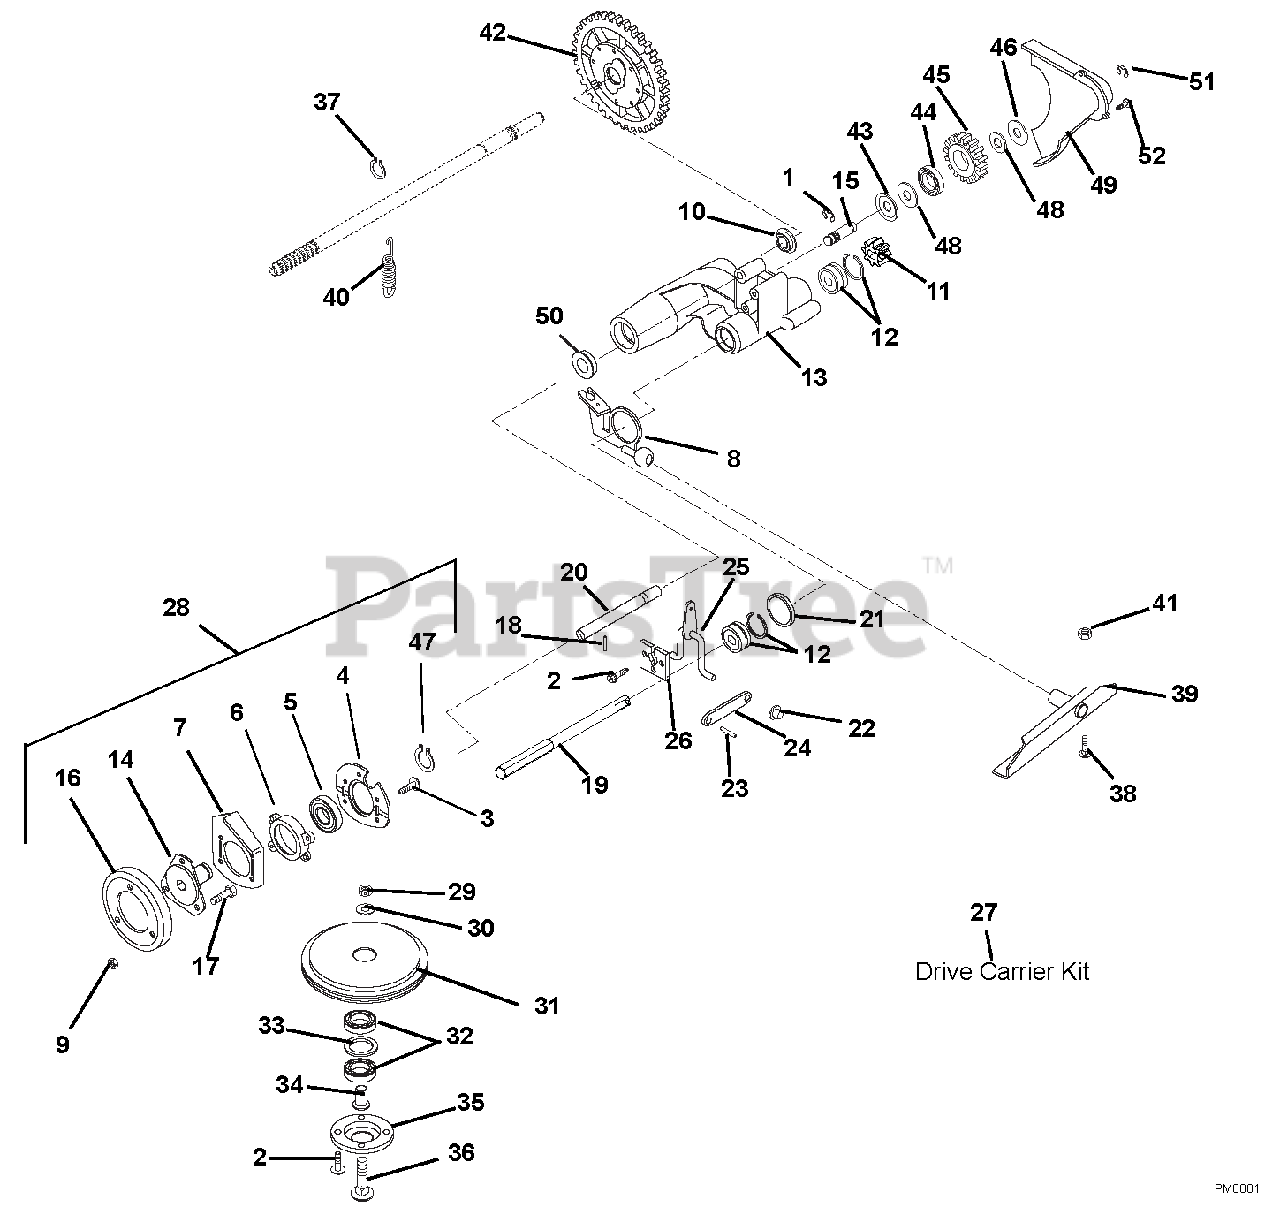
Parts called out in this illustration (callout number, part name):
1	RG-RTNG-EXT .438X.035
2	@SCR-TAP 12-24X.50 HWH TR YWZC
3	SCR-TAP 5HX-0.8X16MM H-FL-YWZC
4	BEARING RETAINER
5	BRG-BALL 1.0X2.0X.56 (1641)
6	BEARING RETAINER
7	PLATE, BEARING
8	ACTUATOR, WBLM DRIVE
9	@NUT-LK-CTR .25-20 YWZC
10	BRG-BALL .625X1.378X.44
11	PINION, D-SHAFT
13	DRIVE CARRIER
14	FRICTION WHEEL HUB
15	IDLER SHAFT
16	DISC, FRICTION - 730 MAT'L
17	@BLT-HEX .25-20X.50 GR5 YWZC
18	PIN-ROLL .188X.88
19	SHAFT, FRICTION DISK
20	ROD - GUIDE
21	WSHR-FL-STL 1.390X2.00X.020 PL
22	PUSH NUT, .25
23	PIN-ROLL .125X.50
24	SHIFT LINK
25	SHIFT ARM WELDMENT
26	RETAINER PLATE
27	KIT, LM DRIVE CARRIER
28	KIT, COM. DRIVE CONVERSION
29	@NUT-LK-CTR .31-18 YWZC
30	WSHR-FL-STL .328X.87X.179 YWZC
31	FRICTION SHEAVE
33	WSHR-FL-STL 1.062X1.344X.032PL
34	SPINDLE - BEARING
35	RETAINER - BEARING
36	@BLT-RDHDSQNK .31-18X1.75 G5YZ
37	RG-RTNG-EXT .579X.035
38	@BLT-RHDSSQNK .31-18X.62 G5YZ
39	PIVOT, CHANNEL WELDMENT
40	SG-TENS .051X.60X2.25 WLD 7.0
41	@NUT-LK-TOP-FLG .31-18 YWZC
42	DIFFERENTIAL ASSEMBLY
43	RETAINER
45	IDLER GEAR
46	WSHR-FL-STL.531X1.00X.063 YWZC
47	RG-RTNG-EXT 1.00X.042
48	WSHR-FL-STL .52X.827X.062 YWZC
49	COVER, GEAR
51	RG-RTNG-EXT .438X.035
52	@SCR-TAP 12-24X.50 HWH TR YWZC
